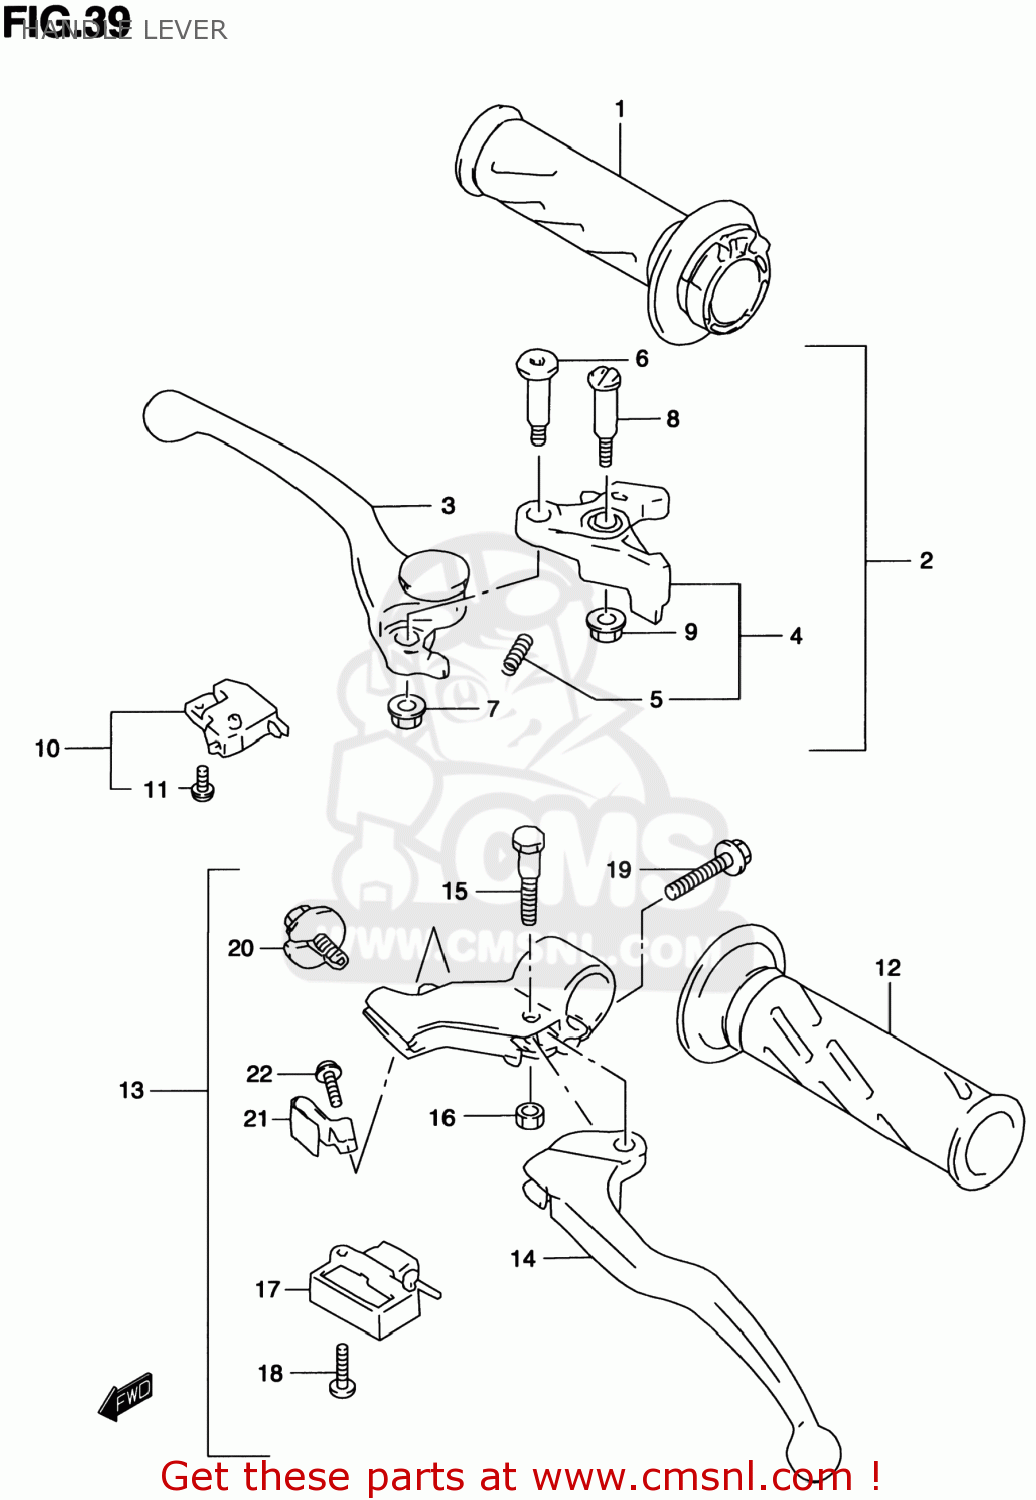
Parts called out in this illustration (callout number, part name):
1	GRIP,THROTTLE
2	LEVER ASSY,BRAKE
3	LEVER,ADJUST
4	KNOCKER
5	SPRING
6	BOLT,LEVER
7	NUT
8	BOLT,LEVER PIVOT
9	NUT
10	SWITCH ASSEMBLY,STOP
11	SCREW
12	GRIP,LEFT
13	LEVER ASSEMBLY,CLUTCH
14	LEVER,CLUTCH
15	BOLT,LEVER SET
16	NUT
17	SWITCH,CLUTCH
18	SCREW
19	SCREW
20	NUT,CABLE ADJUSTER
21	SPRING,ADJUST
22	SCREW,SPRING
